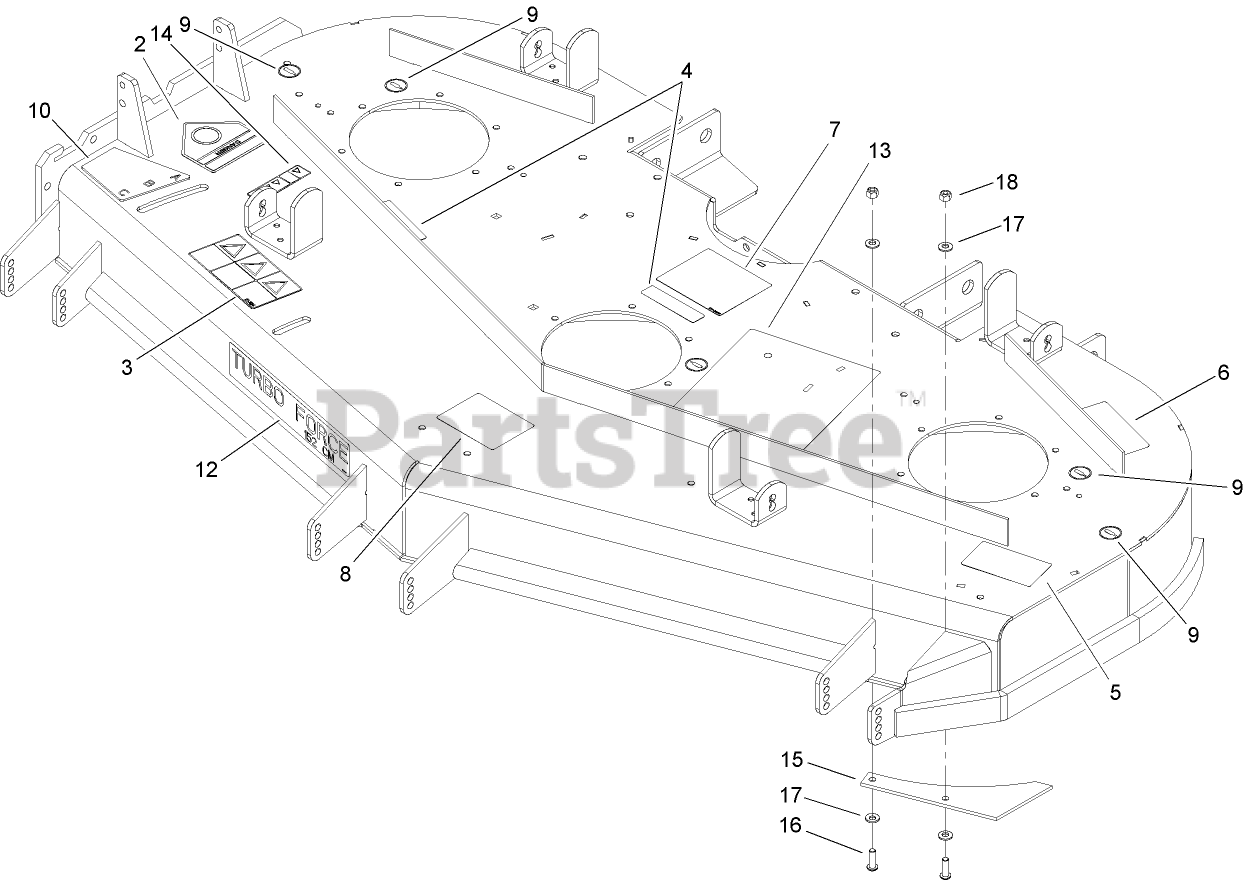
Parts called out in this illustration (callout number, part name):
2	DECAL-DANGER
3	DECAL-DANGER
4	DECAL-WARNING
5	DECAL-DANGER
6	DECAL-TORQUE, BLADE BOLT
7	DECAL-ROUTING, BELT
8	DECAL-ANTI SCALP
9	DECAL-GREASE
10	DECAL-ADJUSTMENT, BAFFLE
13	DECAL-SERVICE, CHECK
14	DECAL-WARNING, DEFLECTOR
15	PLATE-TURBO
16	SCREW-HSBH
17	WASHER-SPRING
18	NUT-LOCK, NI
